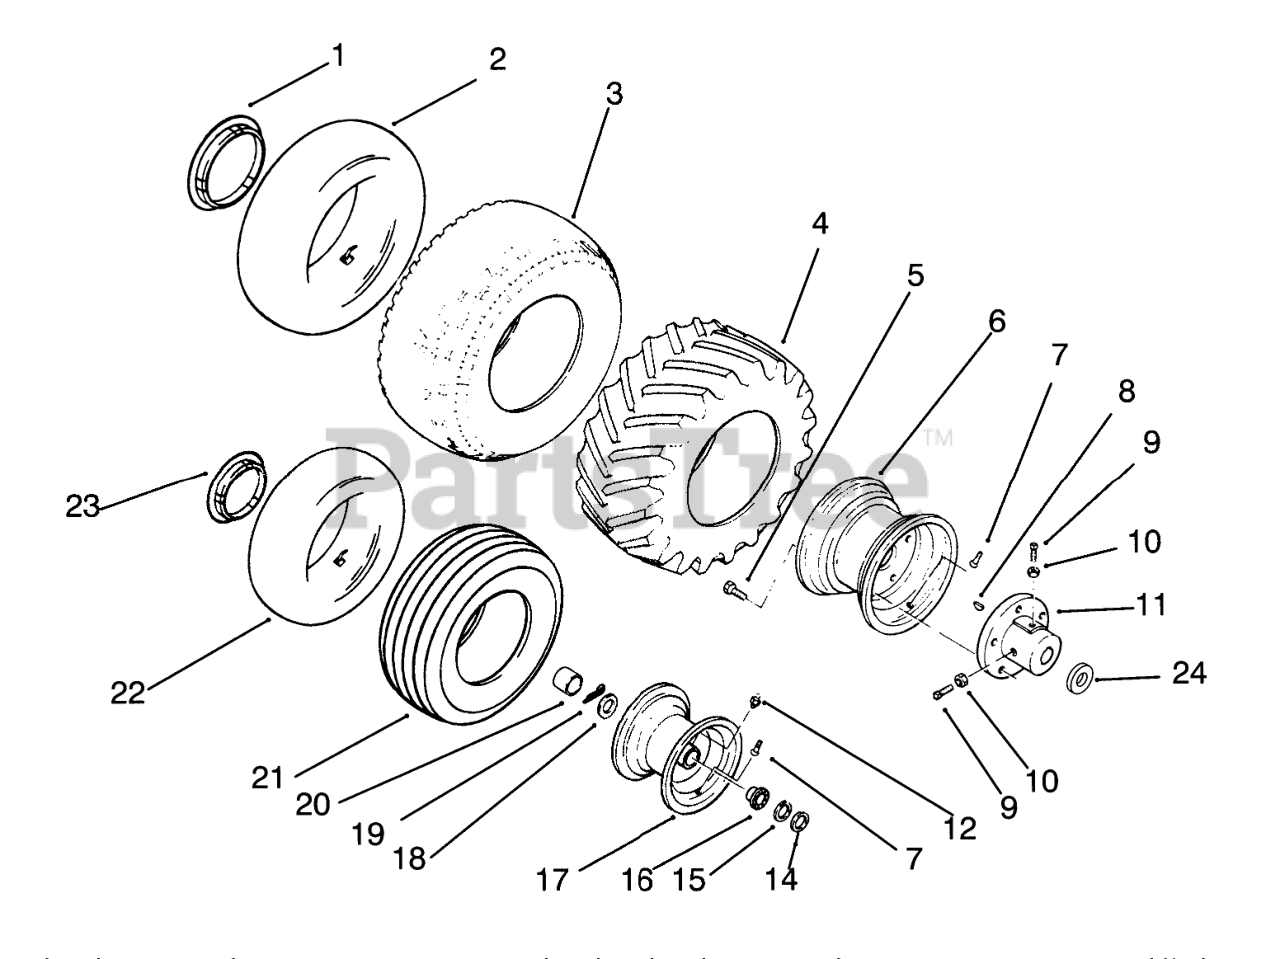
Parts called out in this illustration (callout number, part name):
1	12"-HUB CAP LOGO
2	TUBE-INNER
3	TIRE
4	Tire-Cleat, Rear
5	BOLT-LUG
6	WHEEL
7	VALVE
8	KEY-WOODRUFF
9	SCREW-SET, SQH
10	NUT-JAM
11	Hub Rear
12	ZERK-GREASE
14	WASHER-SHIM
15	WASHER
16	BEARING-WHEEL
17	Wheel Assembly-Front(Incl. Ref. #7, 12, & 16)
18	WASHER WHEEL
19	PIN-COTTER
20	HUBCAP
21	Tire (16 x 6.5-8) 2-Ply -2 Wheel Axel
23	8"-HUB CAP LOGO
24	Washer-Thrust
